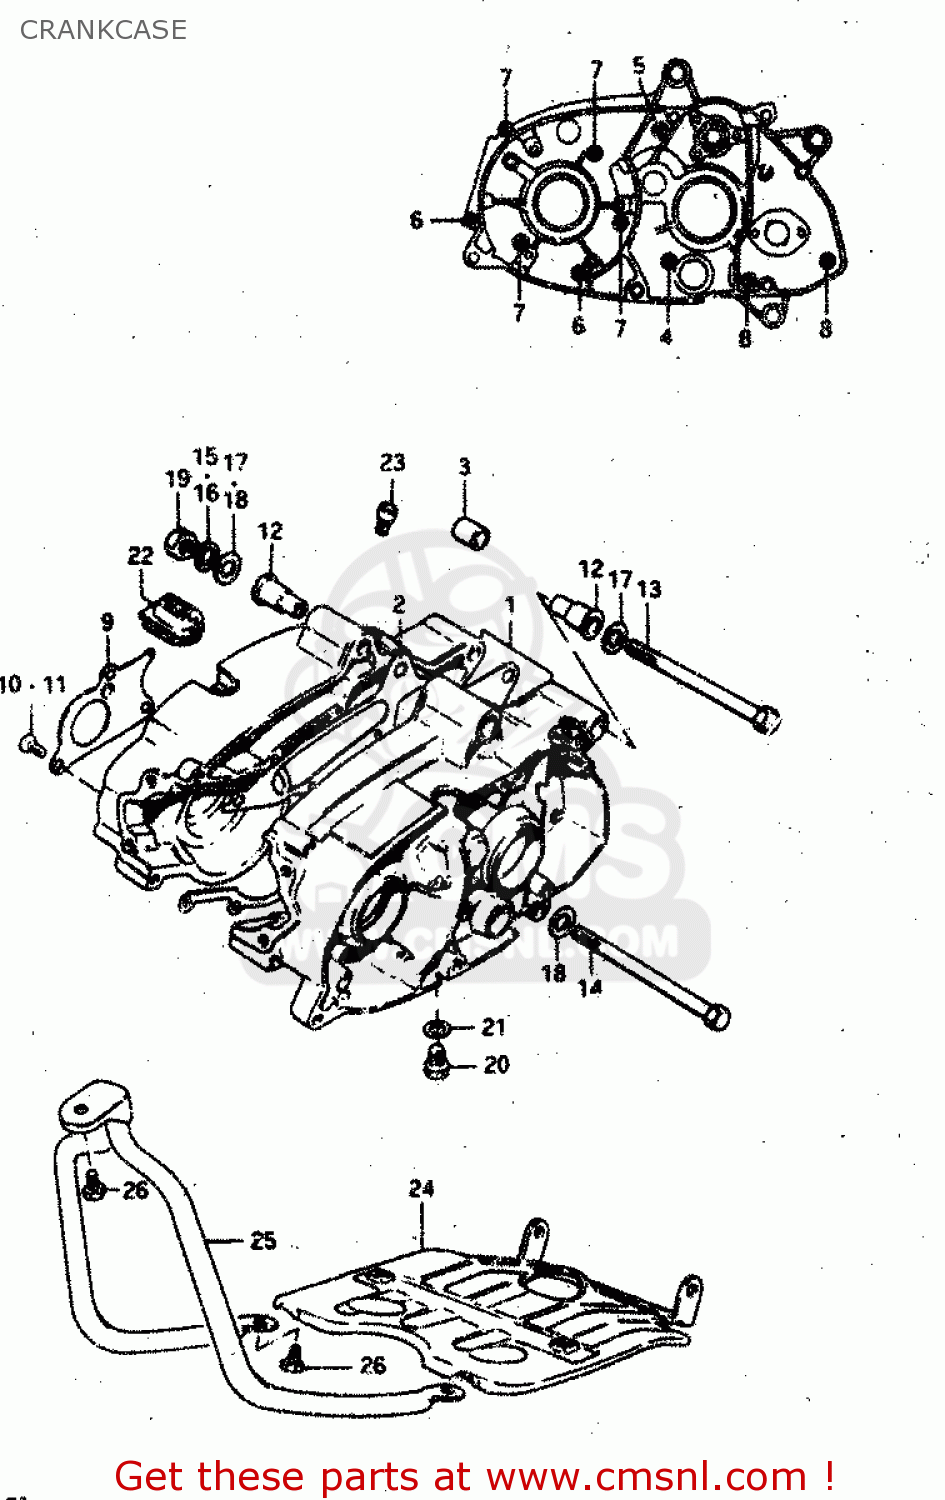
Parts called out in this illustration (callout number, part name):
1	CRANKCASE ASSY
2	GASKET (MCA)
3	PIN
4	SCREW 6X60
5	SCREW
6	SCREW (6X45)
7	SCREW
8	SCREW 6X30
9	PLATE,OIL RESERVOIR
10	SCREW
11	SCREW 6X12
12	BUSH
13	BOLT
14	BOLT(8X145)
15	LOCK WASHER
16	WASHER,LOCK,8.
17	WASHER
18	WASHER
19	NUT
20	PLUG
21	GASKET(10X14X3.6) (NAS)
22	GROMMET
23	CAP(OD:15)
24	PROTECTOR, ENGINE
25	BRACE, PROTECTOR
26	BOLT 8X12
